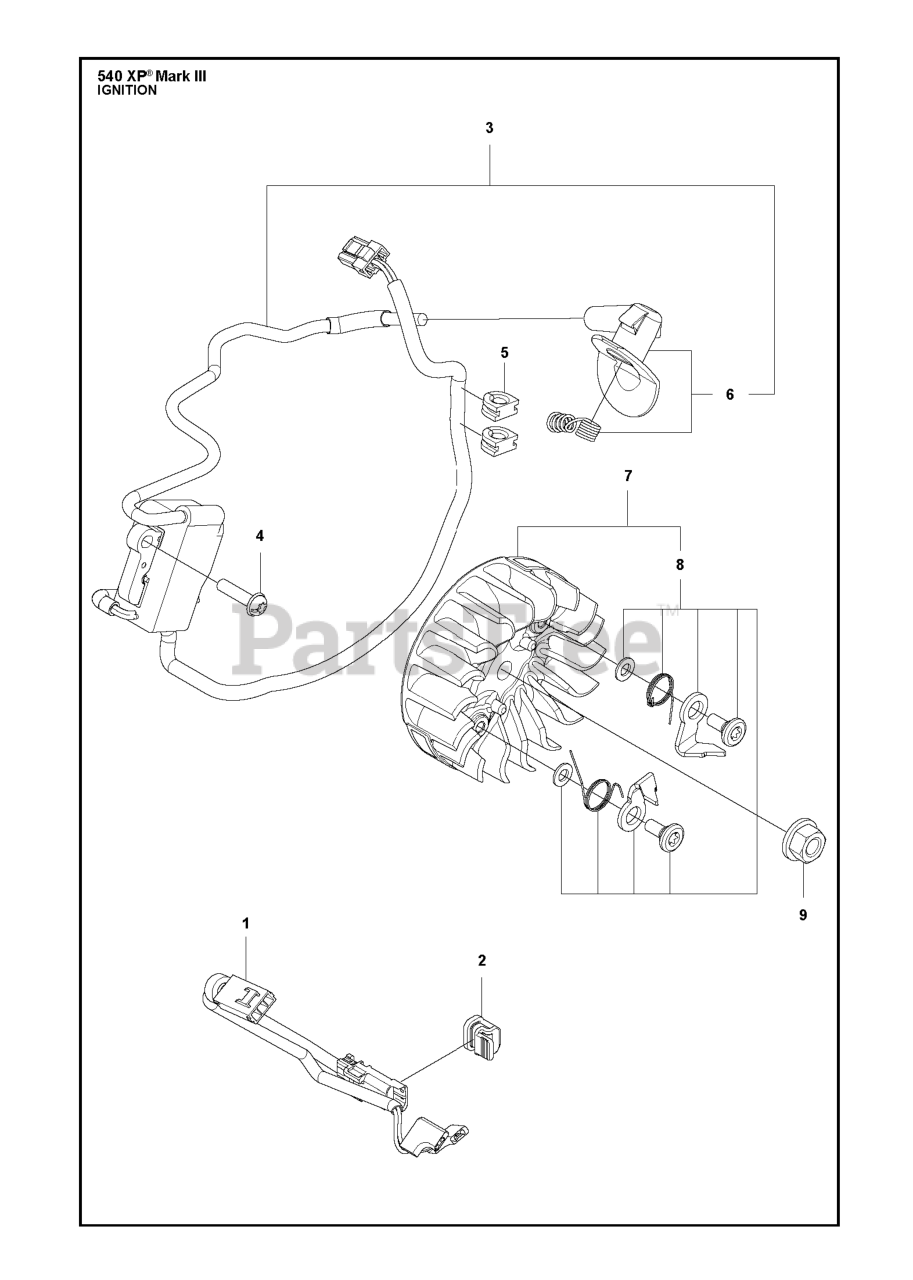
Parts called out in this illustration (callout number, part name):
4	SCREW HEXABOULAR SLOTTED SOCKE
7	FLYWHEEL ASSY D90
9	NUT
